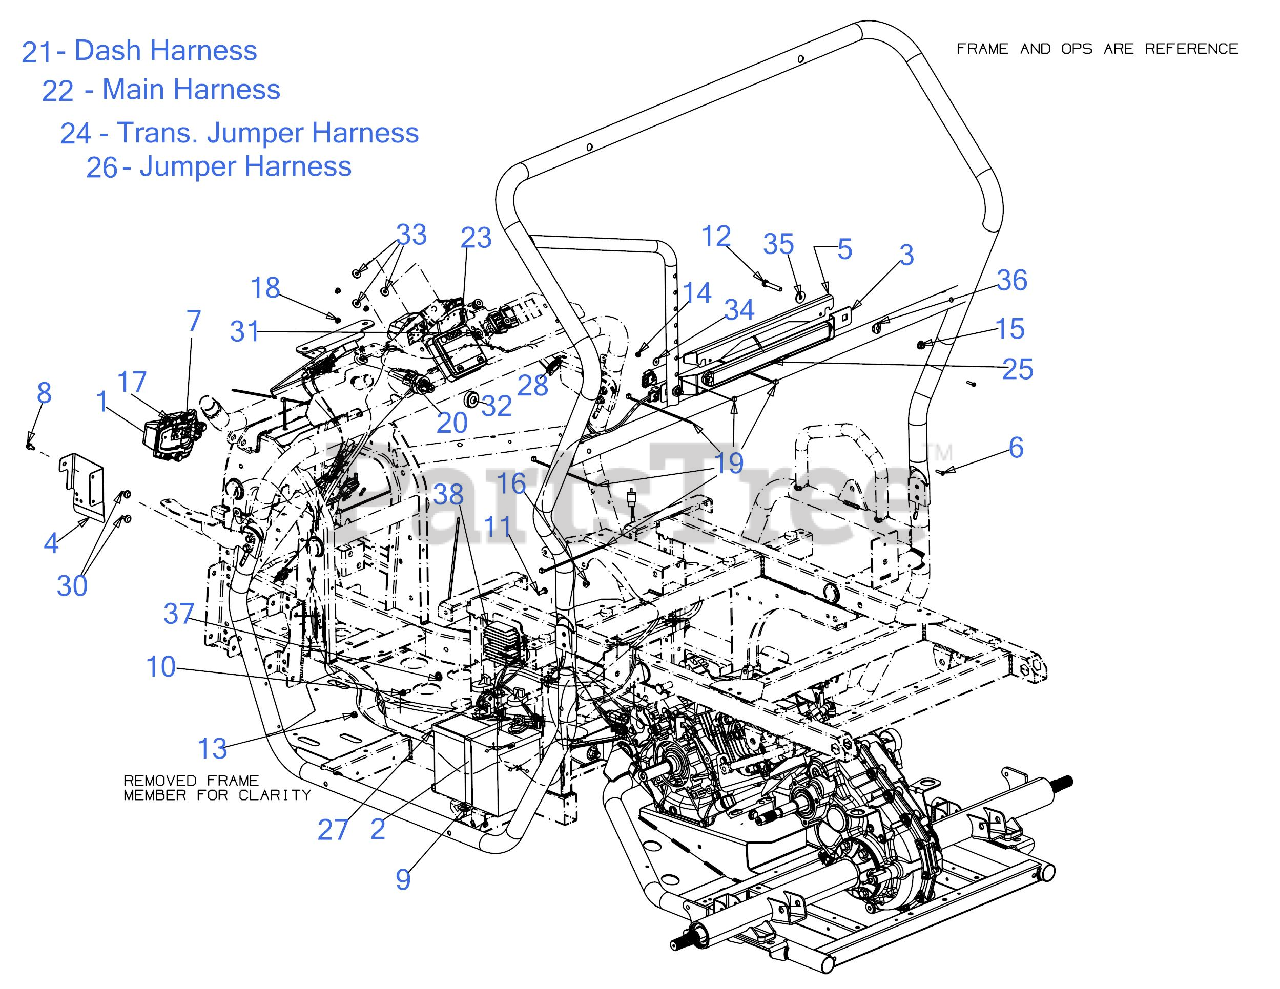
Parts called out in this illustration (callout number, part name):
1	LED HEADLIGHT ASSEMBLY
4	FRONT BRACKET
6	SCREW #8-32 x .750
7	SCREW 1/4-20 X1.00 GR5
8	SCREW 1/4-20 X.500
9	SCREW M6-1 x .625
10	SCREW 1/4-20 x .750
11	SCREW 1/4-20X.75 GR5
12	SCREW 5/16-18 x 1.75 GR5
13	SEMS NUT 1/4-20
15	FLANGE LOCK NUT 5/16-18
16	FLANGE LOCK NUT
17	SQUARE NUT 1/4-20
19	7" CABLE TIE
20	KEY SWITCH Add 725-06956
21	MAIN WIRING HARNESS
22	MAIN WIRE HARNESS
23	INDICATOR GAUGE
24	TRANSAXLE JUMPER HARNESS
25	LED LIGHT WIRE HARNESS
26	JUMPER HARNESS
28	POWER RECEPTICAL
30	RUBBER BUMPER
31	GROMMET .28 X .50 X .50
32	KEY SWITCH COVER
33	FLAT WASHER .28 ID x .74 OD x .063
34	FLAT WASHER .194x.620x.063
35	FLAT WASHER 1.0 OD:.331 ID
36	SADDLE WASHER
